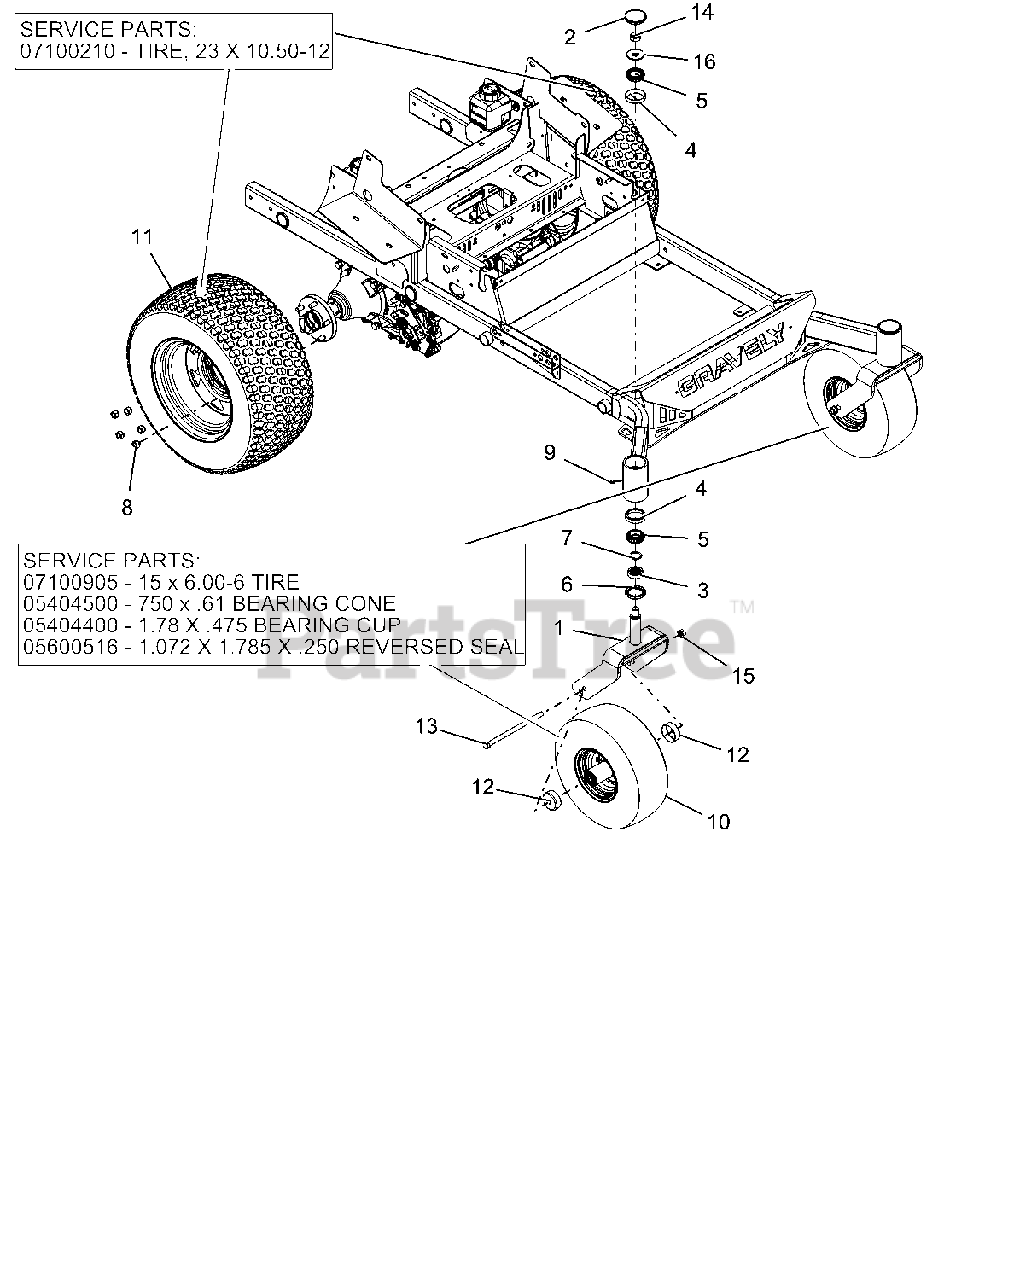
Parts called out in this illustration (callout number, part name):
1	CASTER FORK WMT - RED
2	CAP, DUST
3	SPACER, FRONT CASTER FORK
4	BRG-CUP 2.328X.465
5	BRG-CONE 1.25X.66
6	SEAL, OIL 1.75 X 2.332 X .312
8	WHEEL NUT .500-20 YZ
9	FTG, .25-28 FLUSH MNT GREASE
10	BRG-CONE .750X.61
10	BRG-CUP 1.781X.475
10	TIRE, 15X6-6 SMOOTH
10	SEAL,1.072X1.785X.250 REVERSED
10	ASM, WHL/TIRE 15X6.00-6 SMOOTH
11	TIRE, 23X10.00-12
11	ASM, WHL/TIRE 23X10.50-12 K500
12	SHIELD, WHEEL BEARING
13	BLT-HEX .50-13X9.00 GR5 YWZC
14	NUT-JAM TOPLK .75-16 YWZC
15	NUT-LK-TOP-FLG .50-13 YWZC
16	WSHR-FL-STL.812X2.00X.148YWZC
